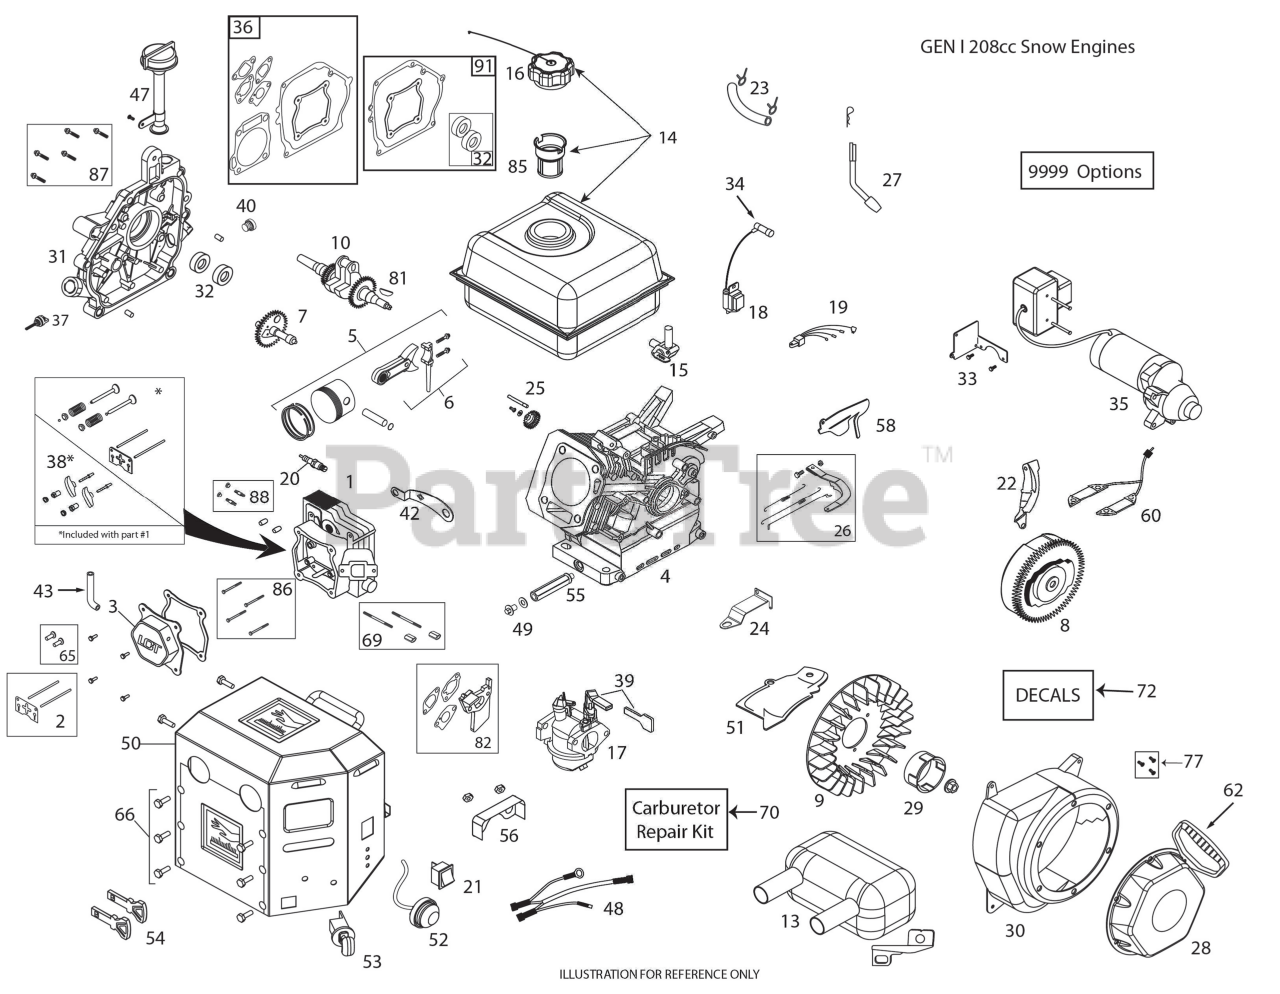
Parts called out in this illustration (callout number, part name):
1	CYLINDR.HEAD.SRV.KIT W/GASKET
2	KIT.PUSH.ROD.SRV(SK208-1001)
3	VALVE COVER ASSEMBLY
5	KIT.PISTON.SRV(SK208-1400)
7	KIT.CAMSHAFT.208CC.LCT
8	FLYWHEEL ELECTRIC START W/6 MA
9	FLYWHEEL FAN 420586
10	CRNKSHFT-KYD#14.208CCSKSNO8001
14	FUEL.TK.ASSY.GENII.SKSN0311.1
15	FUEL.PETCOCK.SNOW(SKSN4900)
16	FUEL CAP OVERSIZED CLICK STYLE
17	CARBURETORS
18	208CC IGN COIL (STD)
20	SPARK.PLUG(2083810)
22	SHIELD.FLYWHEEL.ELEC.STRT.208C
23	FUEL HOSE KIT
24	SPEED.CTRL.BRKT.(SKSN0150)
25	GOVENOR.GEARS ASM(SK2082900)
26	CARBURETTOR GOVERNOR LINK.ASM.
27	KIT.GOVERNOR.CRANK(SK208-3100)
28	RECOIL.STRT.ROUND(BLK) SNOW
29	STRTER.CUP(NON-SLOT)SKSN0601.2
31	COVER CRANKCASE.LCT.SK2083605
32	SEAL KIT (2 PCS)
34	SPARK.PLUG.BOOT.SNW,SKSN4691.1
35	STARTER 230C EL START.LCT SKSN
36	GASKET.KIT.208CC(SK2084300.1)
37	DIPSTICK SMALL
38	ROCKER ARM KIT
39	CHOKE.KNOW.SNOW(SKSN4500)
40	NON REMOVABLE PLUG
43	TUBE.BREATHER.LCT.208
47	TUBE ASSY HIGH OIL-FILL
48	HARNESS WIRE. W/O OFF/ON SWITC
49	KIT.OIL.DRAIN.PLUG(SK2089911
50	BOX HEATER.W/O OFF/ON SWITCH.L
51	SHIELD.CYLINGER.LCT.SKSN0608.1
52	STARTER SCREW.STARTER SWITCH B
53	SWITH.KEY.ASSEM.SNOW.SINGLE.ST
54	KEY SET(2 KEYS) SKSN0407.1
55	EXTENDED OIL DRAIN TUBE
58	SHIELD GOVENOR & CARB - COMPOS
59	FUEL.TNK.SKRT.GENII.SKSN0103.1
60	208CC 60W ALTERNATOR
61	FUEL KNOB-SNOW
65	TAPPET.KIT.LCT.208CC
69	CARB.STUDS & COUPLING KIT.SNOW
70	CARBURETOR.REPAIR KIT.LCT.
72	ARIENS 414 SNOW DECAL KIT
74	MUFFLER GUARD.EUR./LCT.SKSN220
77	BOLT.KIT.RECOIL.LCT.ALL.ENGINE
81	KEYS.FLYWHEEL.208/414CC.5PACK
82	SPACER.CARBURETOR.208CC.LCT
85	STRAINER.FUEL.TANK.LCT.208CC
86	BOLT KIT.CYLINDER HEAD.LCT(4)1
87	KIT.BOLT.CRANKCASE.COVER.6PC
88	STUD.MUFFLER.KIT.LCT
91	COVER CRANKCASE GASKET
97	MUFFLE MANIFOLD GUARD.LCT
9999	KIT.BOLT.LCT.SK9990.1
9999	HIGH.ALTITUDE.JET 6,000FT
